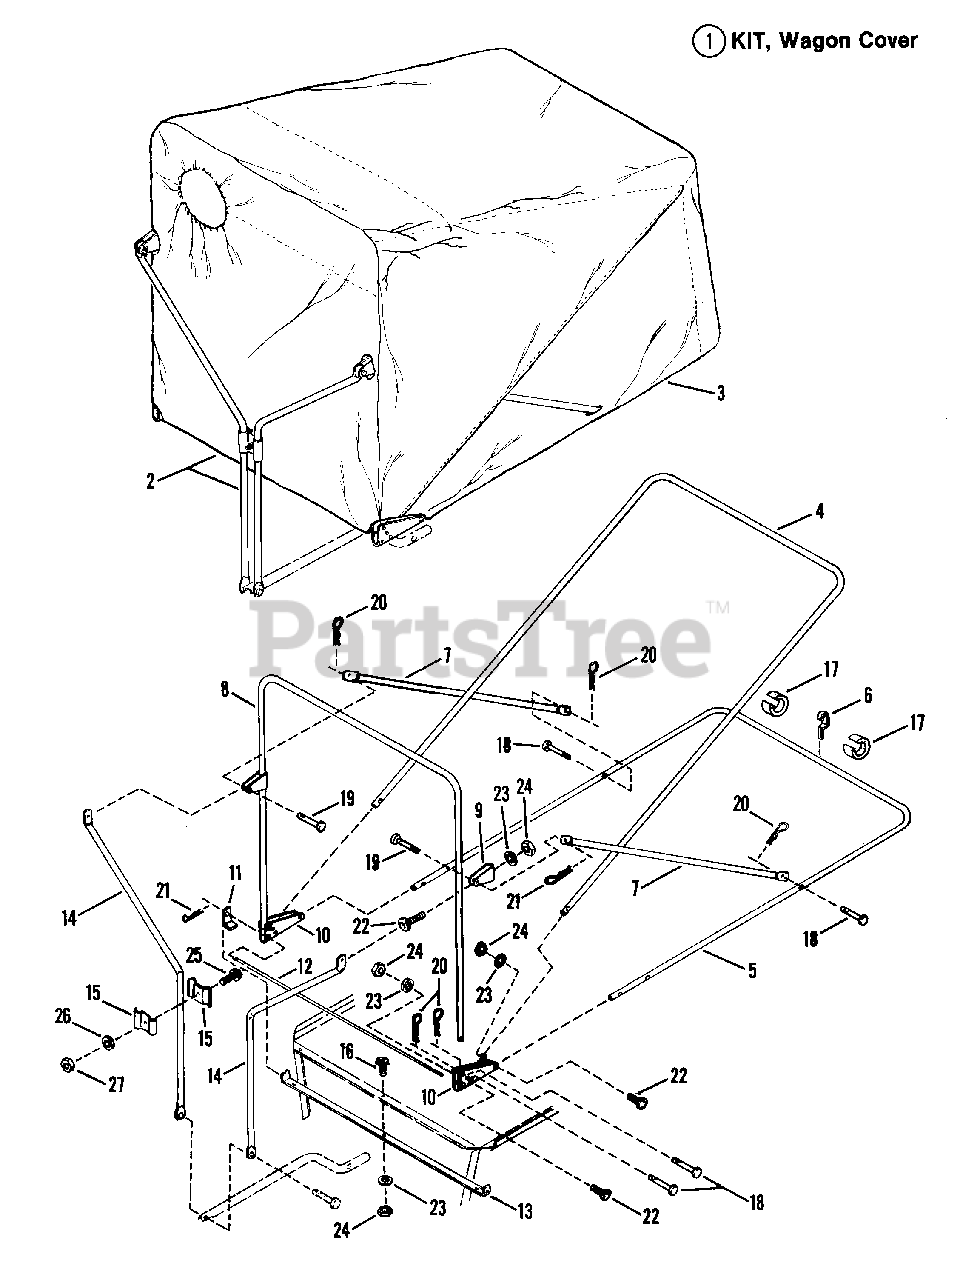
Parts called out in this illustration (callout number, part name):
1	KIT, Wagon Cover
2	FRAME/CANOPY ASSEMBLY
3	CANOPY, Cloth Only
4	FRAME, Center
5	FRAME, Base
6	LOCK, Canopy
7	BRACE, Frame
8	FRAME, Front
9	CLAMP, Rod
10	BRACKET, Corner
11	CLIP, Hinge
12	PIN, Hinge
13	MOUNT, Hinge
14	STRUT, Frame
15	CLAMP, Strut
16	CARRIAGE BOLT, 1/4-20x3/4"
17	BUSHING, Plastic Wear Pads
18	PIN, 1/4x1 1/8" Clevis
19	PIN, 5/16 Clevis
20	PIN, 1/4 hair
21	PIN, Hair
22	CARRIAGE BOLT, 1/4-20x1"
23	LOCKWASHER, 1/4 Internal Tooth
24	NUT, 1/4-20 Hex
25	CAPSCREW, 3/8-24x1"
26	LOCKWASHER, 3/8 Split
27	NUT, 3/8-24 Hex
